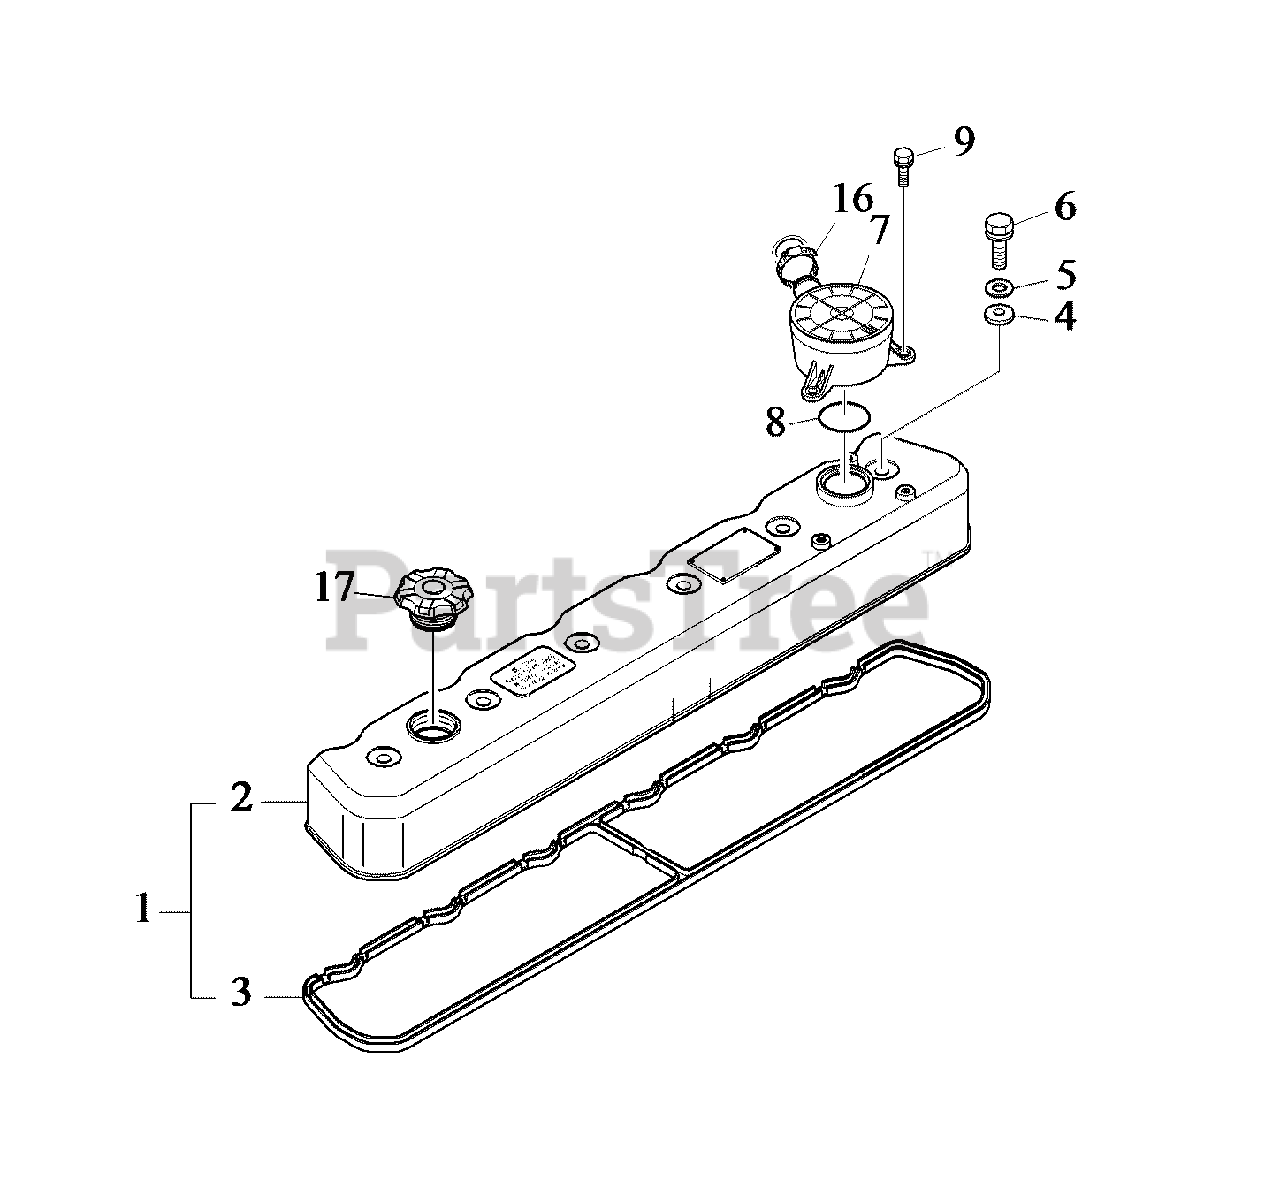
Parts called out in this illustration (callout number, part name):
1	* COVER, CYLINDER HEAD
2	* COVER, CYLINDER HEAD
3	GASKET, W/COVER
4	* SEAL
5	* WASHER
6	* BOLT
7	BREATHER
8	O-RING
9	* BOLT
16	CLAMP, HOSE
17	CAP, OIL
